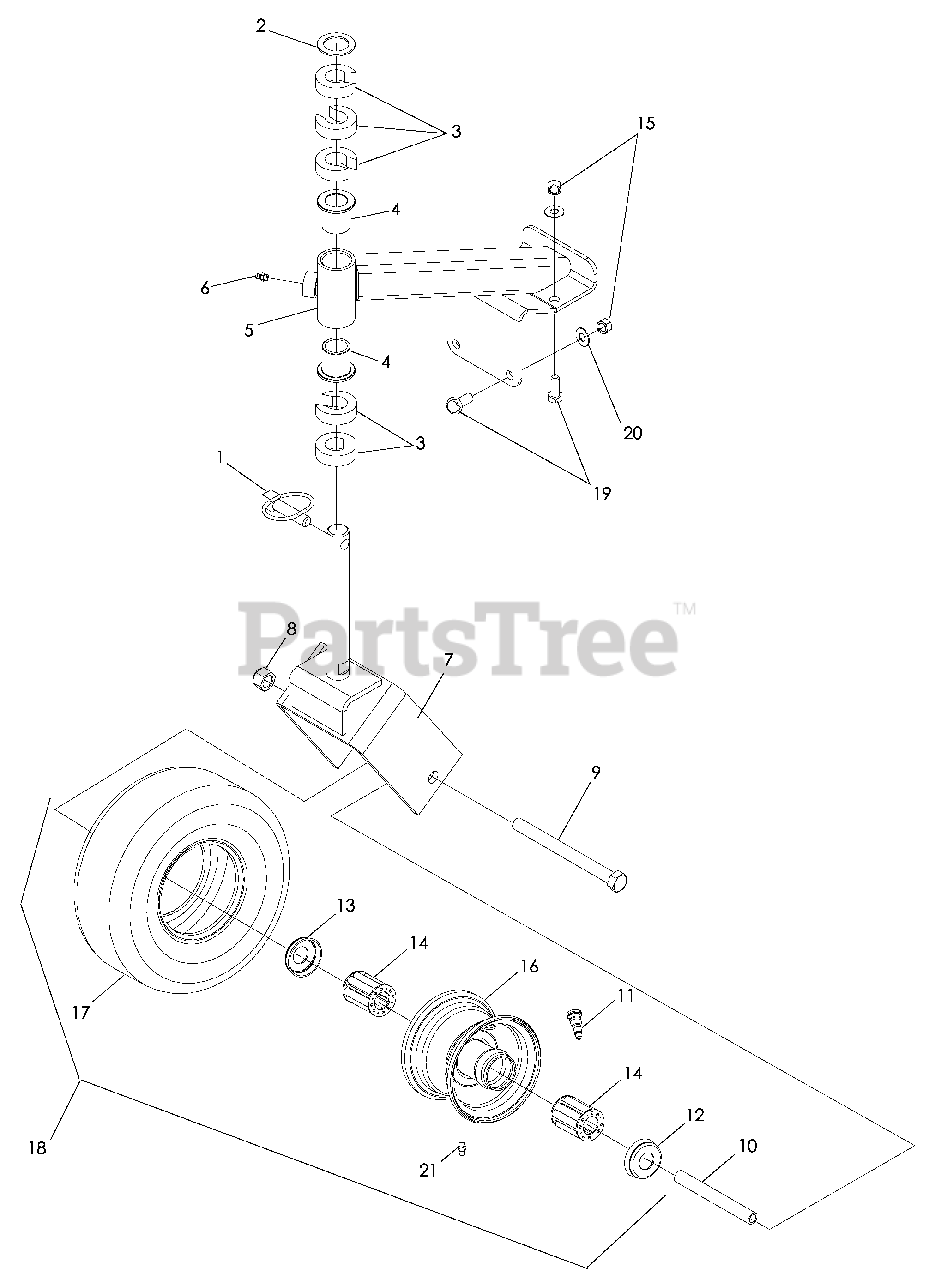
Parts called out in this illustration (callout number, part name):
1	LYNCH PIN 7/16
4	FLANGE BUSHING
5	CASTER ARM W/BUSHING
6	ZERK 1/8 NPT
7	CASTER YOKE
8	NUT ½-13 NYLOC
9	HCS ½-13 x 5½
12	ENDCAP, NOTCHED
13	ENDCAP
14	ROLLER BEARING
15	NUT 3/8-16 CENTERLOCK
18	TIRE & WHEEL
19	HCS 3/8-16 x 1
20	WASHER 3/8
21	ZERK 1/8 NPT
22	FRONT WHEEL CASTER KIT
